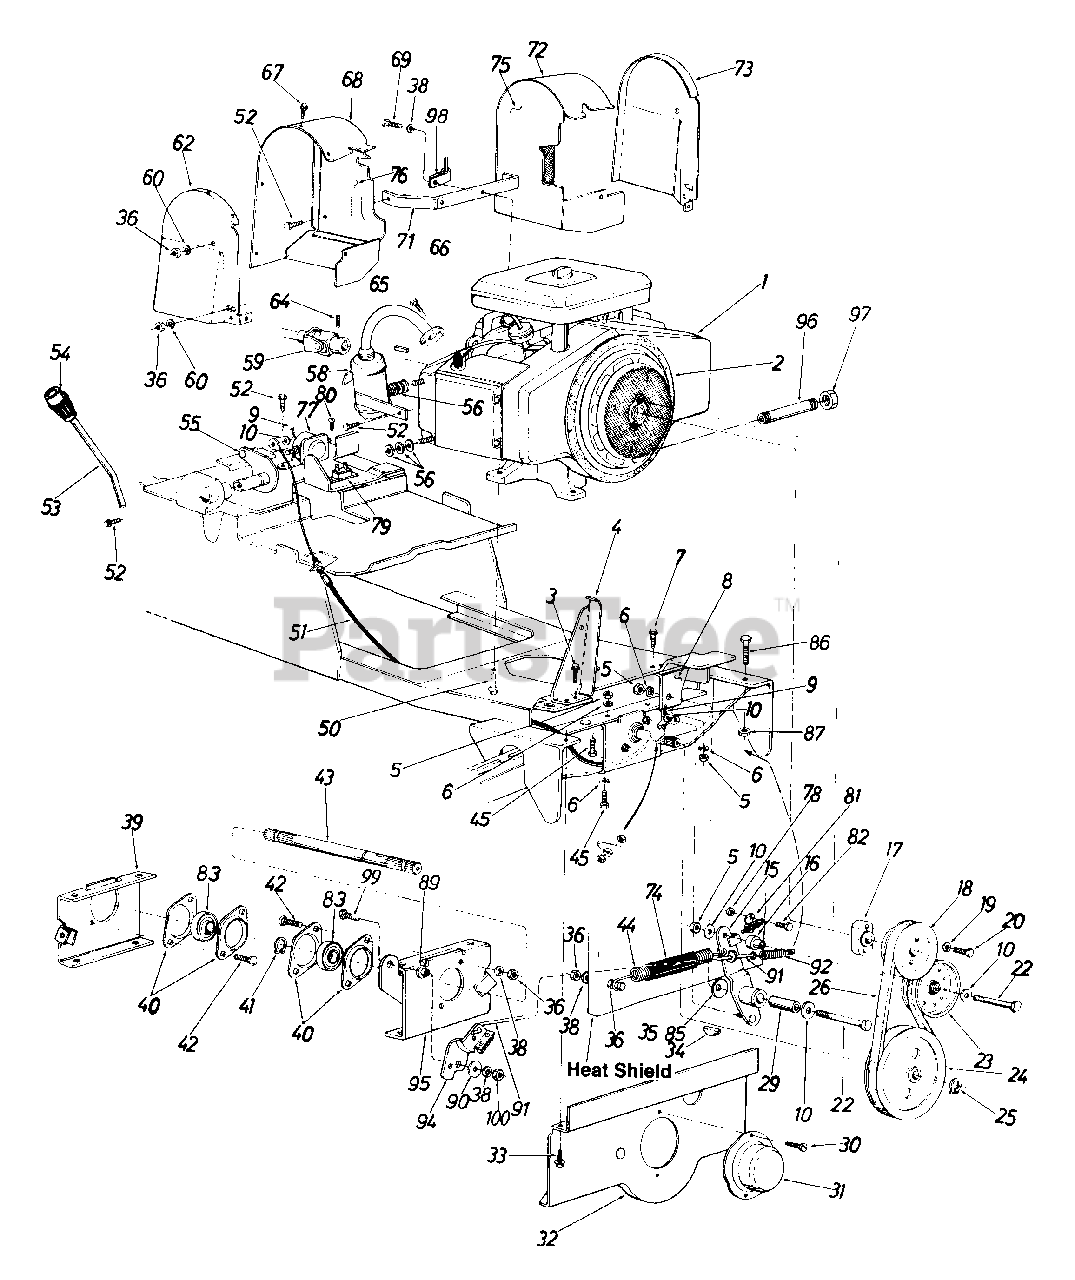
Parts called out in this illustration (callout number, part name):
1	Engine
2	Mylar Foam Strip
3	Hex Wash. Hd. Self-Tap Scr. 1/4-20 x .75" Lg.
6	L-Wash. 3/8" I.D.
7	Hex Wash. Hd. Self-Tap Scr. 5/16-18 x .75" Lg.
10	Fl-Wash. .38" I.D. x 1.25" O.D. x .100" Thk.
17	Pulley Spacer
18	1/2" V-Pulley 4.75" O.D. (Engine)
19	L-Wash. 3/8" I.D. H.D.
20	Hex Scr. 3/8-16 x 2.00" Lg.
22	Hex Bolt 3/8-16 x 2.50" Lg.
23	Flat Idler Pulley
24	1/2" V-Pulley 7.00" O.D. (PTO)
26	"V"-Belt 1/2" x 41" Lg. (PTO)
29	Spacer .375" I.D. x .62" O.D. x 1.830" Lg.
30	Hex "B" Tap Scr. #10 x .50" Lg.
34	#91 Hi-Pro Key
35	Hex Bolt 5/16-18 x 1.25" Lg.
36	Hex Nut 5/16-18 Thd.
38	L-Wash. 5/16" I.D.
40	1.00" Dia. Brg. w/Flangette
42	Carr. Bolt 5/16-18 x .75" Lg.
43	Spline Shaft
44	Extension Spring (PTO Clutch)
45	Hex Scr. 3/8-16 x 1.00" Lg.
50	Hex Wash. Hd. Self-Tap Scr. 3/8-16 x 1.25" Lg.
51	PTO Control Cable
52	Hex Wash. Hd. Self-Tap Scr. 1/4-20 x .50"
55	PTO Actuator Lever Ass'y.
56	Fl-Wash. .312" I.D. x 1.620" O.D. x .060
58	Muffler Ass'y. Comp. - R.H.
59	Universal Joint Ass'y. Comp.
60	Fl-Wash. .312" I.D. x .630" O.D.
62	Shroud Outer - R.H.
64	Sq. Hd. Set Scr. 5/16-18 x .38" Lg. (Cup Point)
65	Sq. Key 1/4" x 2.00" Lg.
66	Hex Wash. Hd. Scr. 1/4-20 x 5/8" Lg. - Grade 5
67	Hex "AB" Tap Scr. #10 x .50" Lg
68	Shroud Cover - R.H.
69	Hex Bolt 5/16-24 x .75" Lg.
71	Shroud Support Brkt.
72	Shroud Cover - L.H.
73	Shroud Outer - L.H.
74	Spring Cover Tubing (PTO Clutch)
75	Shroud Inner Ass'y. - L.H.
76	Shroud Inner Ass'y. - R.H.
77	Solenoid
78	Hex Bolt 1/4-20 x 1/2" Lg.
79	Circuit Breaker
80	Truss Mach. Scr. #10 x .50" Lg.
81	Safety Switch (PTO)
82	L-Wash. 1/4" I.D.
83	Ball Bearing
85	Bell-Wash. .39" I.D. x 1.13"
86	Hex Bolt 3/8-16 x 1.5" Lg.'
87	Hex Cent. L-Nut 3/8-16 Thd.
89	Shoulder Spacer
90	Fl-Wash. .33" I.D. x 1.25" O.D.
91	PTO Brake Rod
92	Extension Spring 2.15" Lg.
95	PTO Brg. Retainer Brkt. Ass'y.
96	Pipe Nipple 3/8" x 5" Lg.
97	Oil Drain Cap
99	Hex Bolt 5/16-24 x .75" Lg.
100	Hex Nut 5/16-24 Thd.
